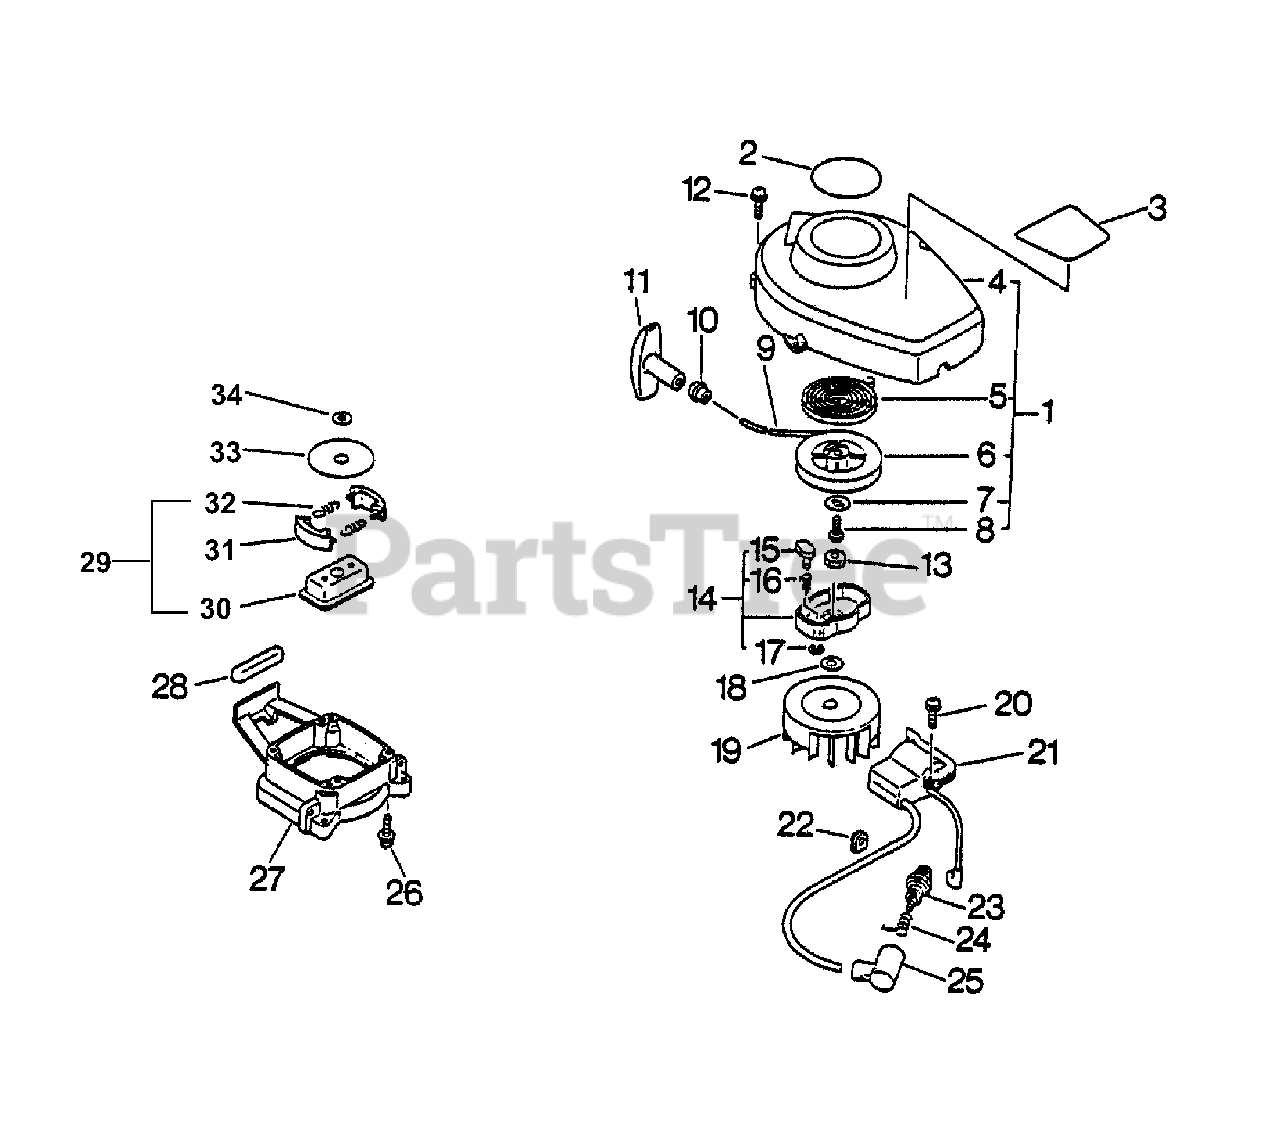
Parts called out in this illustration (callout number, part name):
1	STARTER ASSY
2	LABEL - ECHO
3	LABEL - MODEL HC-2100
4	CASE, STARTER
5	SPRING, REWIND
6	REEL, ROPE
7	WASHER
9	ROPE, STARTER - 3X890
10	GUIDE, ROPE
11	GRIP, STARTER
12	SCREW - 4X16
13	NUT - LEFT HAND
14	STARTER PAWL ASSY
15	PAWL, STARTER
16	SPRING, RETURN
17	RING, RETAINING - 4
18	WASHER - 8
19	FLYWHEEL
20	SCREW - 4X22
21	COIL, IGNITION
23	SPARK PLUG -- BPM-7A
23	SPARK PLUG -- RCJ-7Y
24	TERMINAL, SPARK PLUG CAP
25	CAP, SPARK PLUG
26	SCREW - 4X16
27	CASE, CLUTCH
28	CUSHION, FUEL TANK
29	CLUTCH ASSY
30	HUB, CLUTCH
31	SHOE, CLUTCH
32	SPRING, CLUTCH
33	PLATE, CLUTCH
34	WASHER, CLUTCH
